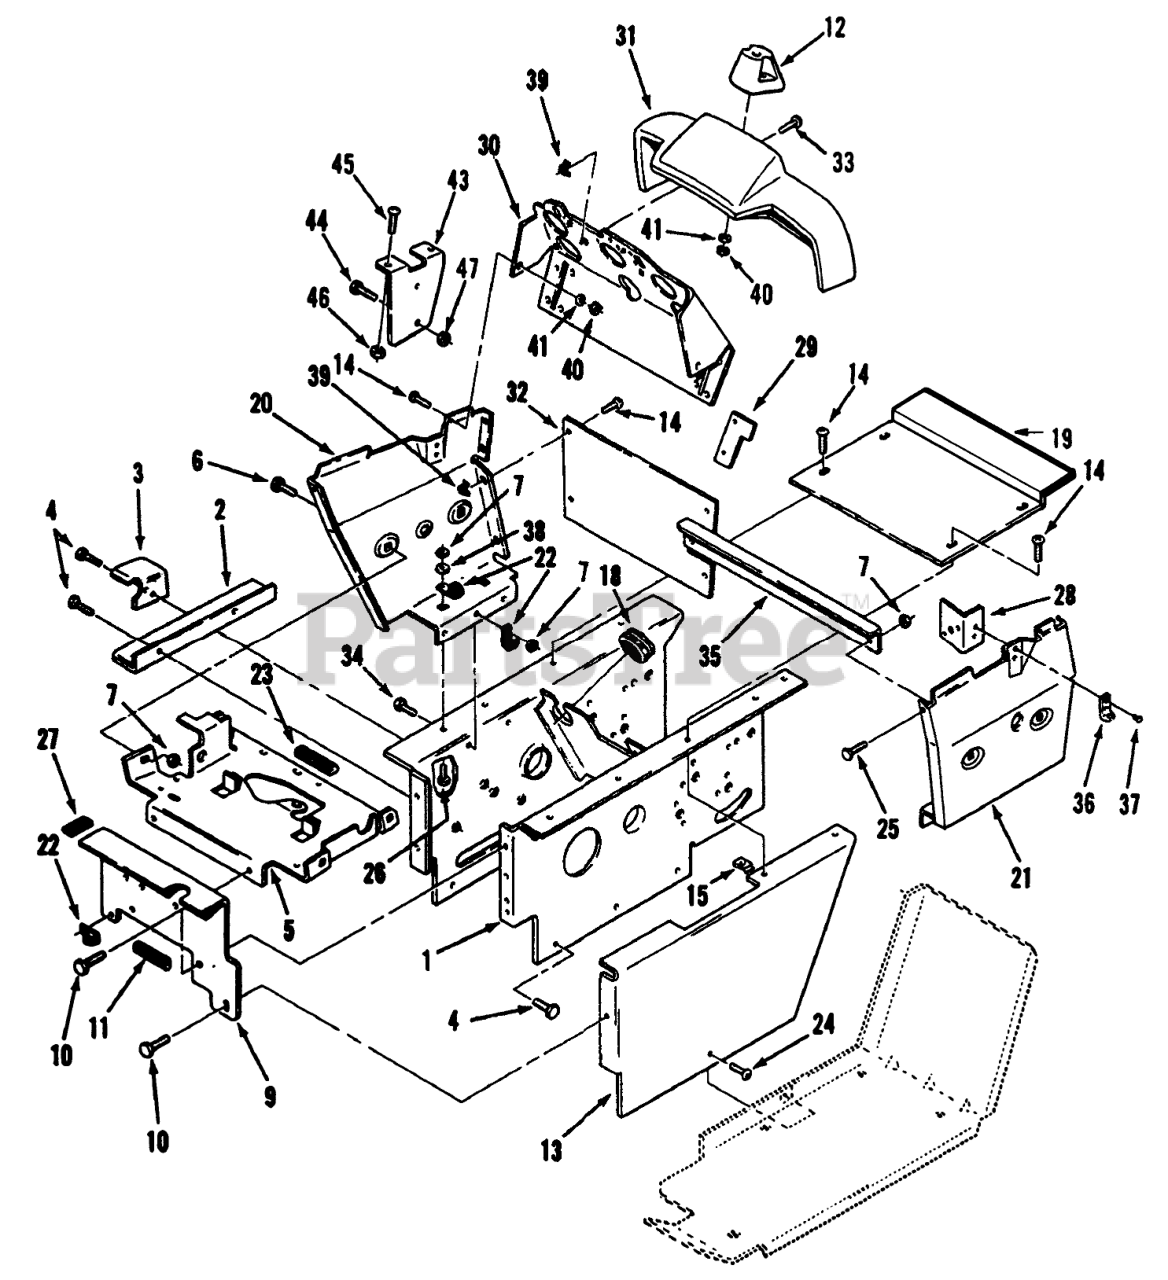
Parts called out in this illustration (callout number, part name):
1	Hoodstand
2	ANGLE-BELT GUARD B
3	Belt Bracket
4	SCREW
5	WLD-SUPPORTB
6	BOLT-CARR
7	NUT-LOCK, NI
9	Plate-Front
10	SCREW
11	EDGE TRIM 2" 102896
12	COVER-STEERING SHAFT
13	Cover-Side LH
14	Screw
18	GROMMET
19	Plate-Top Hoodstand
20	Panel-RH
21	Panel-LH
22	CLIP
23	EDGE TRIM 5" OF 102896
24	Screw
25	SCREW-HH
26	CARRIAGE BOLT -4
27	EDGE TRIM-BULK
28	BRACKET-SWITCH SU
29	STOP-CHOKE
30	ASM-Panel
31	Kit-Console Cover (Contains #115620 5-Gauge Cover, #118410 Steering Cover, (4) 118780 Screw #6 Plastite, & (4) 920270 Washers)
32	Plate-Hoodstand
33	Screw
34	SCREW-HH
35	STIFFENER-PANEL B
36	Keeper-Latch (Included in 106825 Hood Latch)
37	RIVET
38	WASHER-PLAIN
39	NUT-RETAINED
40	NUT-LOCK, NI
41	WASHER-FLAT
43	Bracket-Holder
45	SCREW-HH
46	Nut
47	NUT-LOCK, NI
